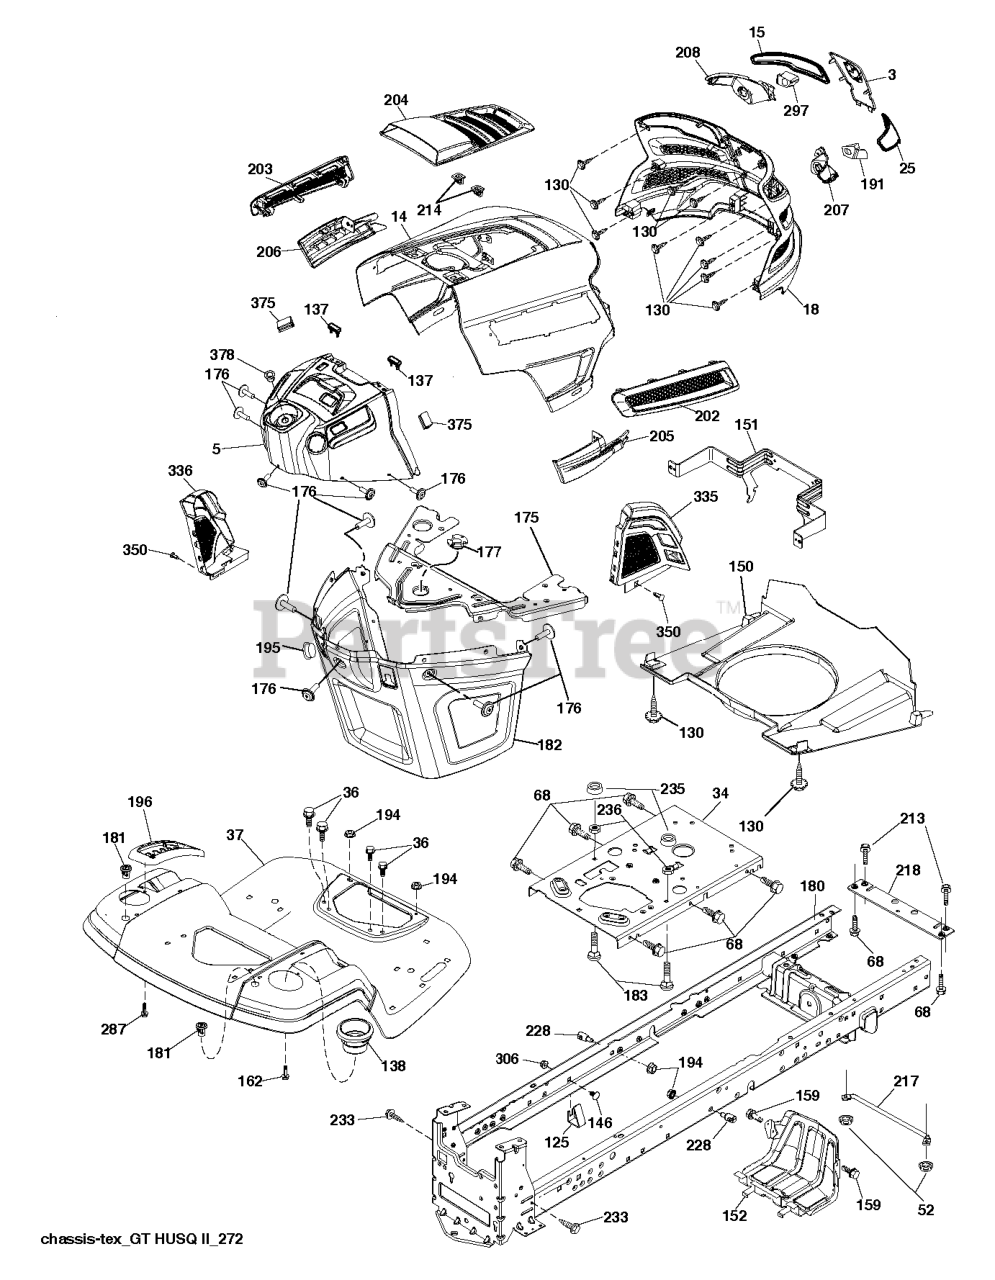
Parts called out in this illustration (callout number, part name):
3	APPLIQUE.SUBASM.GT.HUSQ.II
5	DASHBOARD.UPPER.ASM.GT2.498
14	HOOD.ASM.HUSQVARNA.GT.TEX.ORAN
15	LENS.HEADLIGHT.LH.GTII.2011
18	GRILLE SUBASM.GT.II.LOW.HDLGHT
25	LENS.HEADLIGHT.RH.GTII.2011
34	PLATE.ENGINE.WELDED.CHASSIS
36	SCREW 5/16"
37	FENDER.TLT.PDL.CNTRL.W/CPH.ORG
125	CLIP.FUEL.LINE
137	BUMPER DASH
138	CUPHOLDER.TL.TEX.BLACK
146	BOLT.RDHD.SHT.SQNK.3/8-16X5/8
150	AIR.DUCT.GTV.BLACK
151	BRACKET.PIVOT.HOOD.GT.HUSQ.II
152	SHIELD.BROWNING.PNT.GT.V2
159	SCREW
175	PLATE.PNT.CROSSMEMBER.HUSQ/PRE
176	SCREW.#10-24X5/8.RN.QU
177	BUSHING STEERING
180	CHASSIS
181	BUSHING.MNT.FEND.CRGO.TEX.49
182	DASH.LOWER.COMMON.12V.ADAPTOR
191	INSERT.REFLECTIVE.RH.HUSQ.GTII
195	PLUG.HOLE.DASH.LOWER.12V.BLK
196	DECKLFT.CONSOL FULL ASSM GREY
202	VENT.SIDE.RH.GT.HUSQ.II.
203	VENT.SIDE.LH.GT.HUSQ.II.498
204	VENT.TOP.HUSQ.GT2
205	SIDE.TRIM.RH.GT.HUSQ.II
206	SIDE.TRIM.LH.GT.HUSQ.II.GRAY
207	HEADLIGHT.CUP.BEZEL.HUS.GT2.RH
208	HEADLIGHT.CUP.BEZEL.HUS.GT2.LH
213	SCREW HEXAGON HEAD SCREW 5/16-
214	CLIP.RETAINER.TINNER.
217	ROD.PIVOT.HOOD
218	X-PIECE.HOOD.STOP.NON/
228	STUD.FASTNER.W/ANTI-ROTATE
233	BOLT.SHOULDER
236	NUT.CENTERLOCK.5/16-
287	SCREW 1/4X20
297	INSERT.REFLECTIVE.LH.HUSQ.GTII
306	NUT LOCK FLG 3/8-16 UNC
335	COVER.LOWER.DASH.RH.BLACK
336	COVER-LH.LOWER.DASH.GT2.BLACK
350	CLIP.X-MAS.TREE
375	BUMPER CLIP-ON. DASH 1"
378	BUSHING FLANGE; PLASTIC
